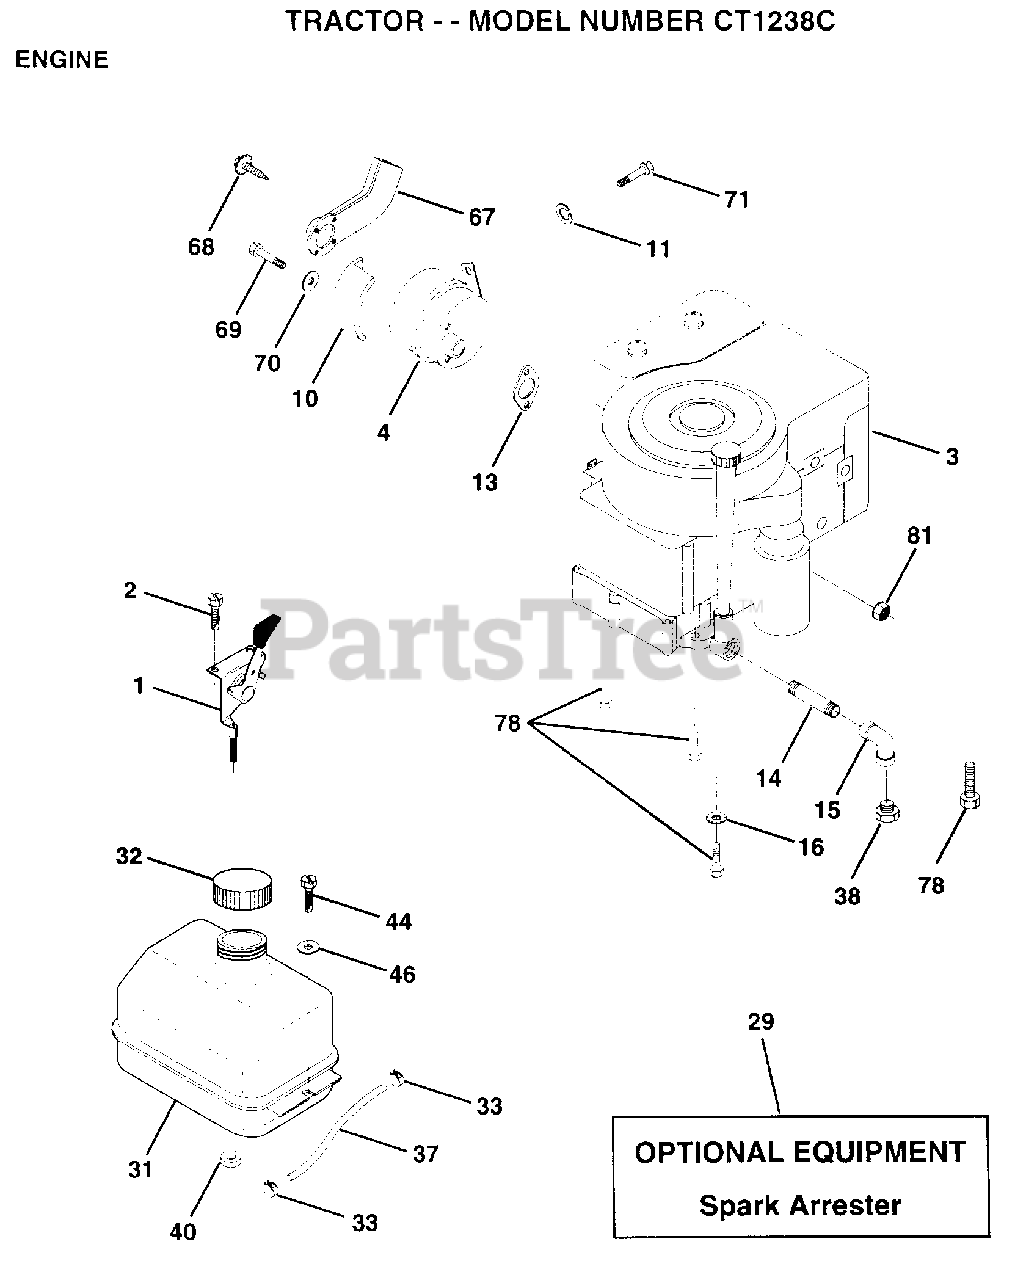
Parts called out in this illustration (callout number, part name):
1	THROTTLE CONTROL
2	SCREW LT
3	ENG B&S 10-12.5HP PWRBLT DC
4	MUFFLER LTV
10	SHIELD HEAT LTV
11	LOCKWASHER
13	GASKET ENG 1 313 LD TIN PLATED
14	PIPE NIPPLE
15	ELBOW
16	LOCKWASHER
31	TANK.FUEL.LT.
32	CAP ASM FUEL
33	HOSE CLAMP
37	LINE FUEL
44	SCREW HEX CRT
46	WASHER
67	DEFLECTOR MUFFLER
69	"BOLT,HEX"
70	WASHER T
71	BOLT HXHD FIN
78	SCREW
81	NUT
